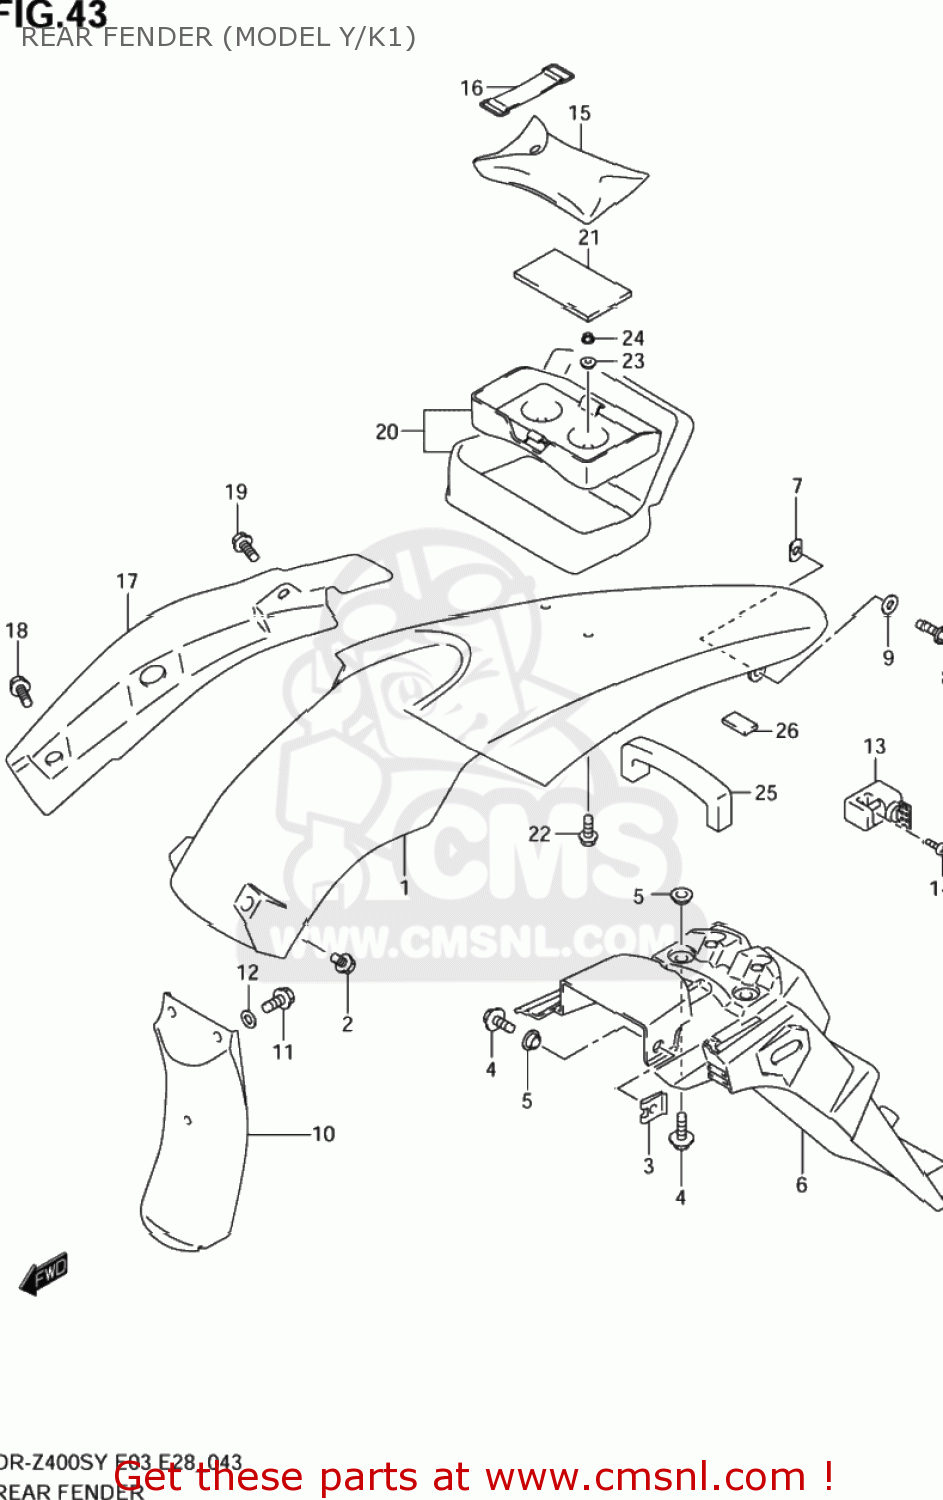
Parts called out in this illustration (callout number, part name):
1	FENDER,REAR
2	BOLT(6X16)
3	PLATE,REAR FENDER FITTING
4	BOLT(6X20)
5	WASHER
6	EXTENSION,RR FENDER
7	NUT,COWL
8	BOLT
9	WASHER (5X14X1)
10	MUDGUARD,RR FENDER FR
11	BOLT
12	WASHER
13	LOCK SET,HELMET
14	SCREW(6X14)
15	TOOL ASSY
16	BAND
17	MUDGUARD,RR FENDER,R
18	BOLT,MUD GUARD LOWER,RIGHT
19	BOLT
20	BAG ASSEMBLY,SEAT TAIL
21	CUSHION,RR BAG
22	BOLT
23	WASHER
24	NUT
25	SEALER,SIDE COVER L
26	PROTECTOR(170X95X3.0)
